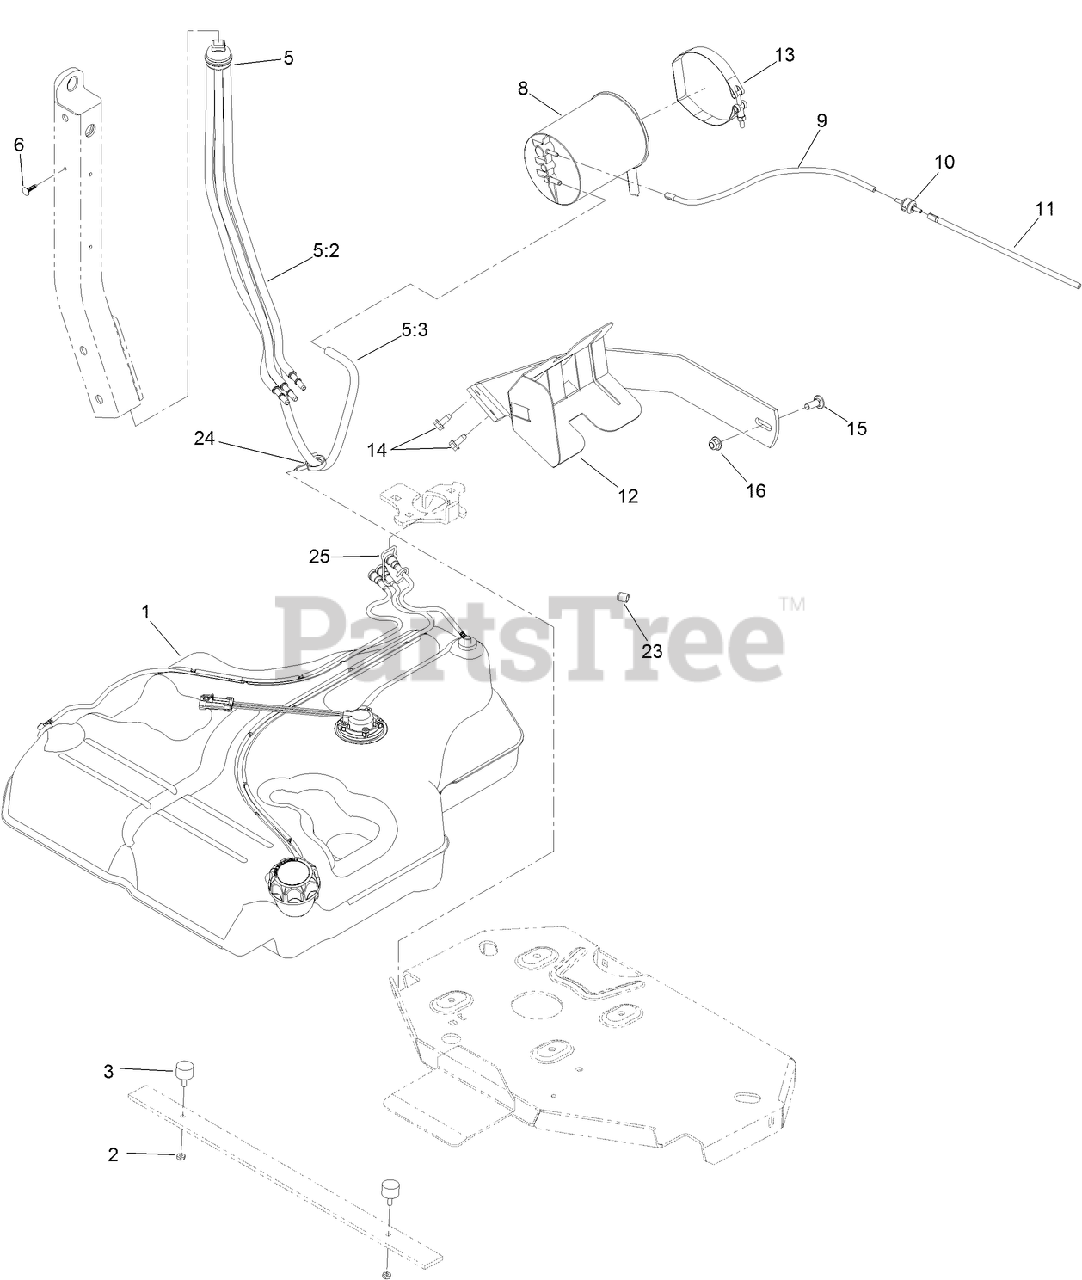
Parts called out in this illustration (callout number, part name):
1	FUEL TANK ASM
2	NUT-JAM
3	BUMPER-RUBBER (W/ STUD)
5	FUEL MANIFOLD VENT ASM
5:2	HOSE-FUEL
5:3	HOSE-FUEL
6	PLUG-PLASTIC
8	CANISTER-CARBON, 1200CC
9	HOSE-VENT, FORMED
10	VALVE-CHECK, VACUUM
11	HOSE-VENT, FORMED
12	MOUNT-CANISTER
13	CLAMP-T-BOLT
14	SCREW-HWHTF
15	SCREW-CARR
16	NUT-HF, NI
23	PLUG-PORT
24	CLAMP-HOSE
25	RETAINER-LINE, VAPOR
